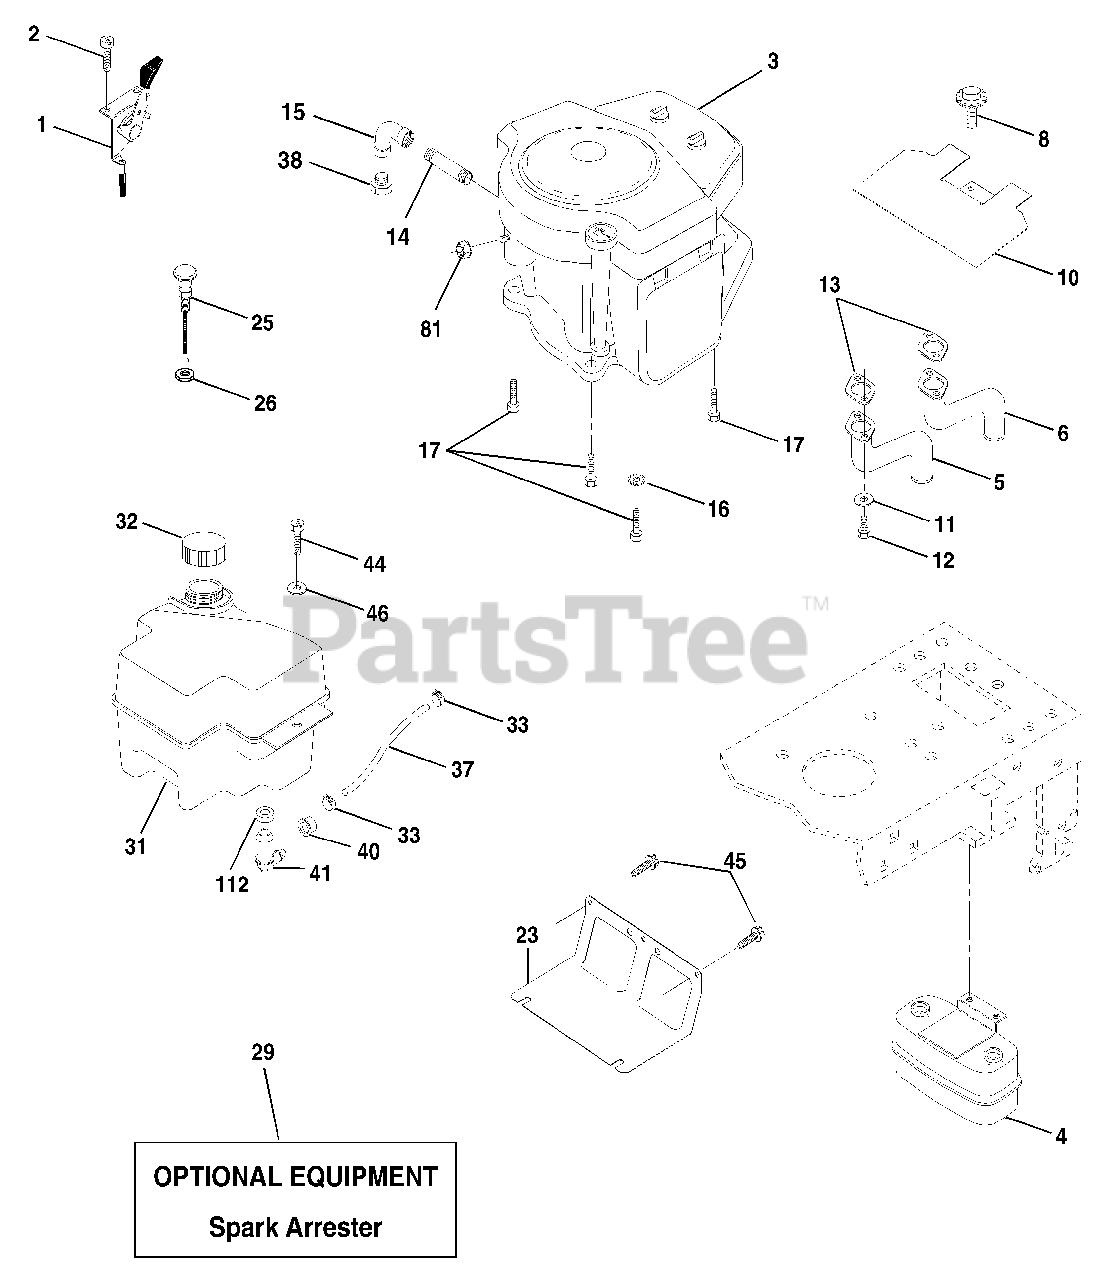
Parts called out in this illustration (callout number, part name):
1	Control Th/ch Flag
2	Screw Hex Thd Cut 1/4-20 x 5/8 T
4	Muffler Exhaust
5	Exhaust Tube LH
6	Exhaust Tube RH
8	Bolt 5/16-18 UNC x 3/4
10	Shield Browning
11	Washer Lock 5/16
12	Screw Hex 5/16-18 x 3/4
13	Gasket Muffler
14	Nipple Pipe 3/8 NPT x 3
15	Elbow STD 90 Degree 3/8-18
16	Washer Lock Ext Tooth 3/8
17	Screw 3/8-16 x 1-1/2
23	Shield Brn/Dbr Guard
25	Control Choke
26	Nut Keps 3/8-24 Unf
29	Arrestor Spark
31	Tank Fuel Front 2 00
32	Cap Fuel
33	Clamp Hose Black
37	Line Fuel 20"
38	Plug Oil Drain
40	Bushing Snap Nyl Blk Fuel Line
41	Stem Tank Fuel
44	Screw Hex wsh Thdrol 1/4-20 x 3/4
45	Screw Hex Wsh Thdrol 3/8-16 x 3/4
46	Washer 9/32 X 7/8 X 16 Ga
81	Nut Keps Hex 1/4-20 Unc
112	Bushing
